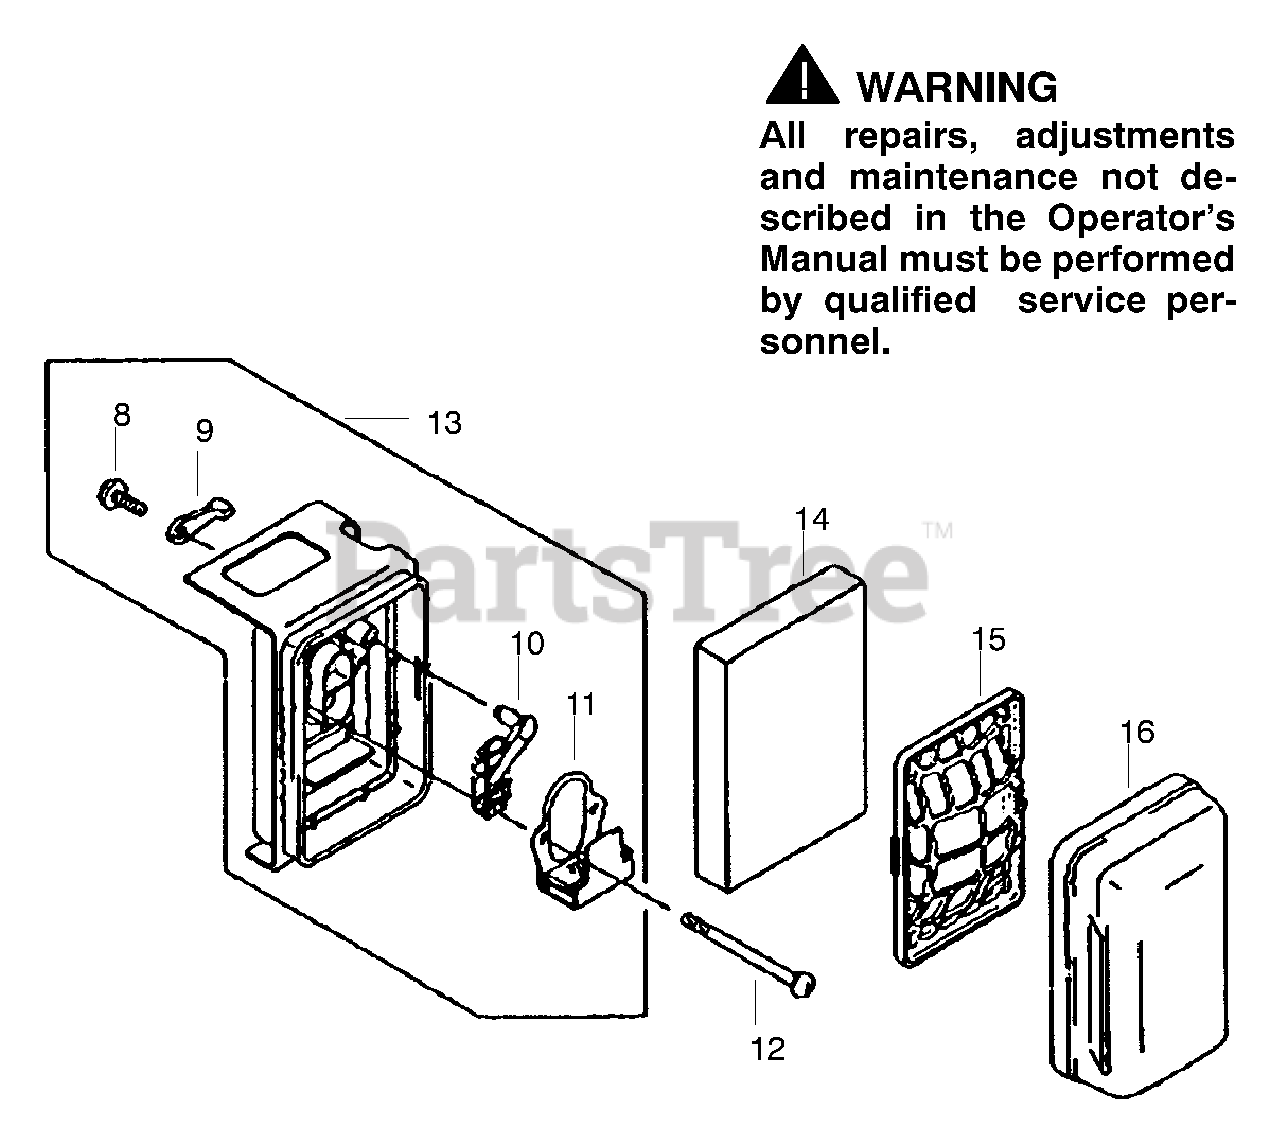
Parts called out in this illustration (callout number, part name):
8	Screw-3x10
12	Screw-5x65
13	Assy-Air Filter Case
14	Element-Air Filter
